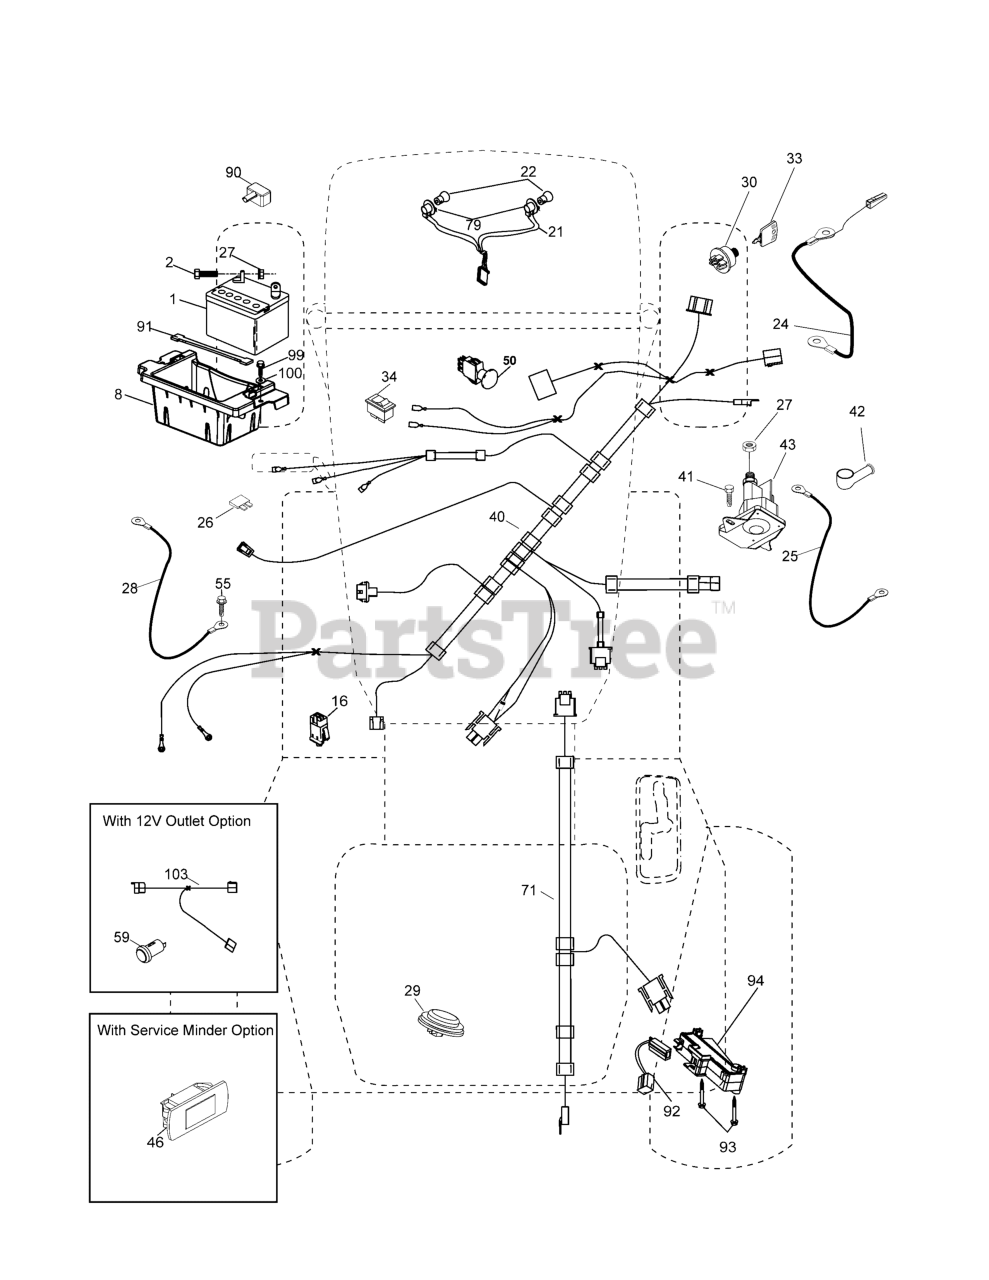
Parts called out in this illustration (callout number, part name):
1	Battery
2	Bolt Hex Hd 1/4-20 unc x 3/4
8	Box Battery
16	Switch Interlock
21	Harness Socket Light w/4152J
22	Bulb, Light #1156
24	Cable Battery
25	Cable Starter
26	Fuse
27	Nut Keps Hex 1/4-20 unc
28	Cable Ground
29	Switch Seat
30	Switch Ign
33	Key/Chain
34	Switch Light/Reset
40	Harness Dash
41	Screw 1/4-20 unc x 1/2
42	Cover Terminal Red
43	Solenoid
46	Gauge Hourmeter
50	Switch PTO
55	Screw 5/16-18 x 3/4
59	Outlet 12-Volt
71	Harness Ign. Chass.
79	Socket Asm. Bulb
90	Cover Terminal
91	Strap Battery Mount Front
92	Harness Pigtail Reverse Switch
93	Screw Plastic 10-14 x 2.0
94	Module Reverse ROS
99	Screw Hexwsh Thdrol 1/4-20 x 3/4
100	Washer 9/32 x 7/8 x 16 Ga.
103	Harness Pigtail 12V Outlet
